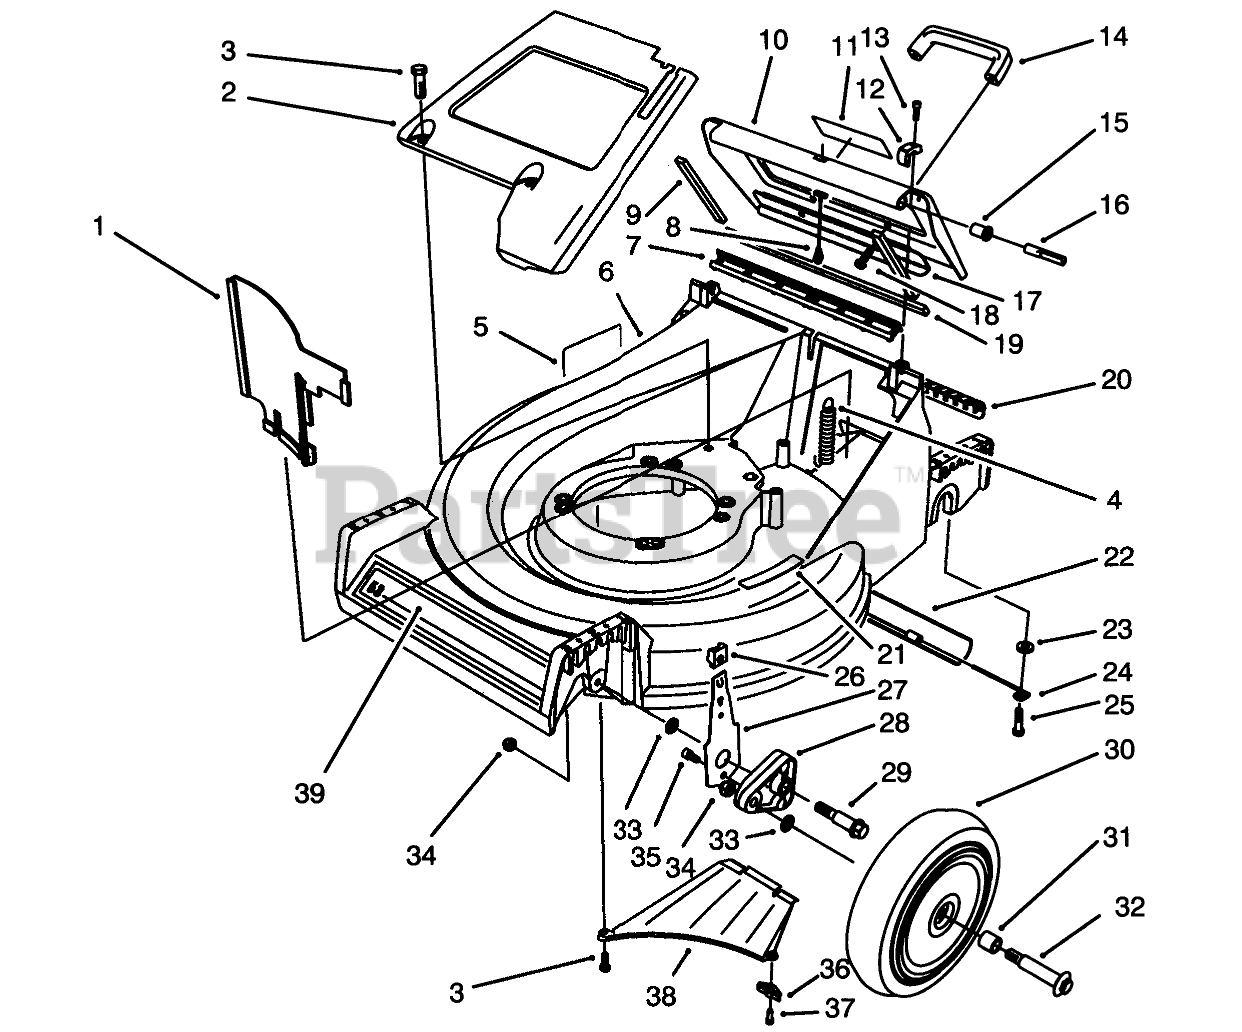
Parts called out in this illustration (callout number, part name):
1	PANEL-VERTICAL
2	PaneI-Screen
3	SCREW-HWHTF
4	EXTENSION-SPRING
5	Decal Danger
6	Housing-53cm (Incl. Ref. #5 & 21)
7	DOOR SEAL
8	DOOR CABLE
9	DOOR SIDE SEAL
10	Door-Discharge (Incl. Ref. #9, 11 & 19)
11	DECAL - DANGER
12	HINGE CLAMP
13	SCREW-HSH
14	HANDLE-DOOR
15	DOOR BUSHING
16	HINGE PIN
17	DOOR - BRACE
18	SCREW-HWH
19	DOOR END SEAL
20	ACCESS COVER
21	DECAL - STEP PAD INT'L
22	TRAILING SHIELD
23	WASHER-PLAIN
24	SHIELD HANGER
25	SCREW-SHOULDER
26	KNOB-ARM
27	FRONT SPRING ARM ASM
28	ARM-PIVOT, FRONT
29	Screw-Shoulder
30	Wheel & Tire Assembly (Incl. Ref. #31)
31	BUSHING
32	WHEEL BOLT
33	WASHER
34	NUT-LOCK
35	SCREW-HSH, THREAD FORMING
36	Bracket-Discharge
37	SCREW-HWHTF
38	Ramp Discharge
39	DECAL
